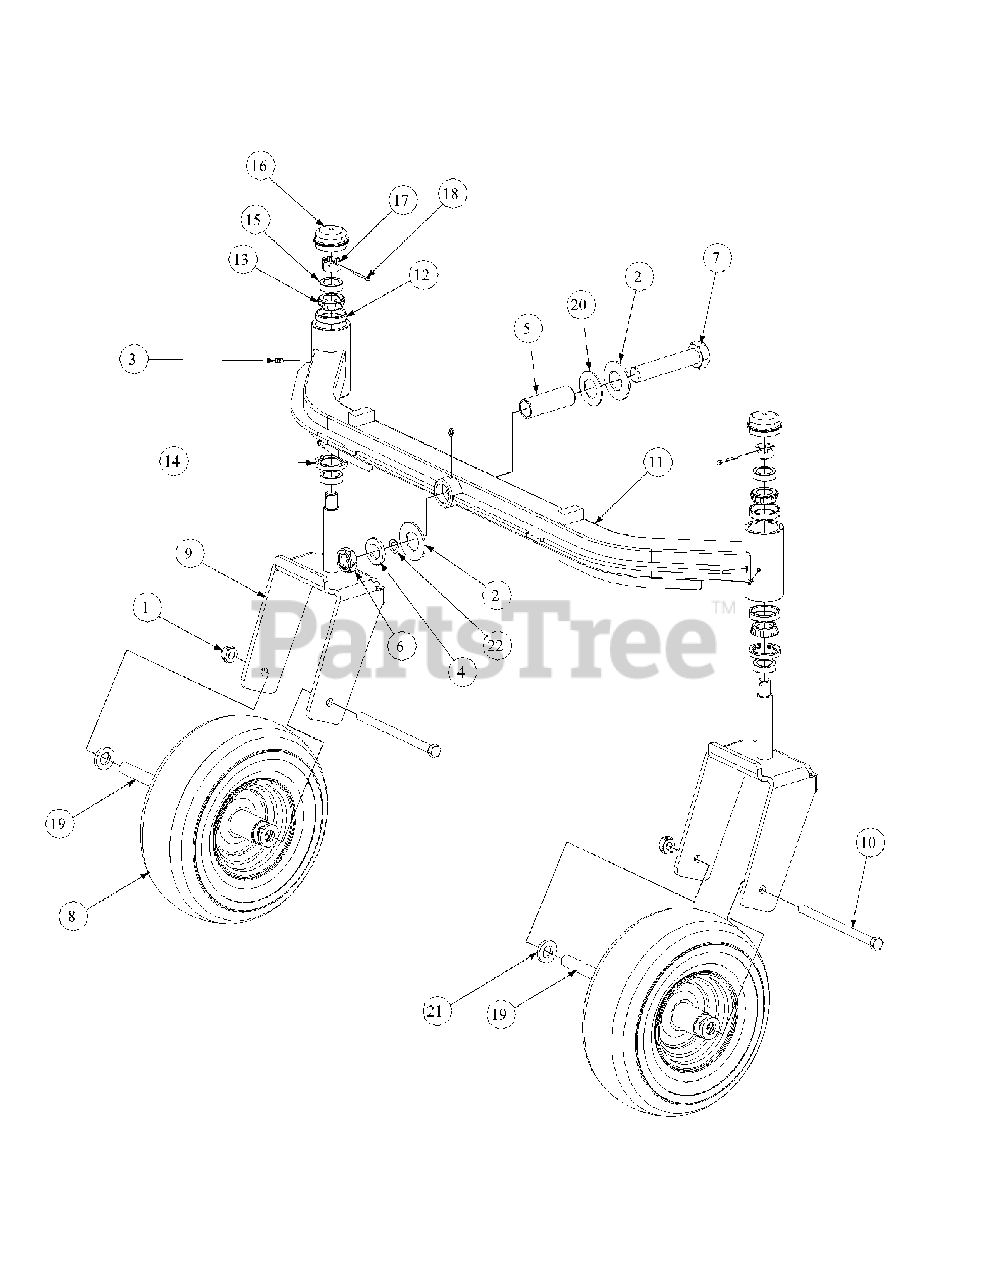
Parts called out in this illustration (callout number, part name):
1	Nut, 1/2-20, Center Lock
2	Bell Washer, 1.25 ID x 2.5 OD x .180
3	Grease Fitting
4	Special Washer
5	Spacer, 1.005 ID x 1.25 OD x 3.6
6	Nut, Jam, 1.0-14, Insert Lock
7	Hex Cap Screw, 1-14 x 5.0
7	Retainer Extension Self Locking
8	Wheel Assembly, 13 x 6.50 x 6, White, includes:
9	Yoke, Caster Wheel
10	HHCS, 1/2-20, 7.50
11	Front Axle Assembly
12	Cup Bearing
13	Bearing Cone
14	Seal
15	Ring Seal
16	Grease Cap, 1.986 OD
17	Slotted Nut, 3/4-16
18	Cotter Pin, 5/32, 1.25
19	Wheel Spacer
20	Flat Washer, 1.25 ID x 2.25 OD x .075
21	Spacer, .812 ID x .218LG
22	Retainer Extension, Self Locking
